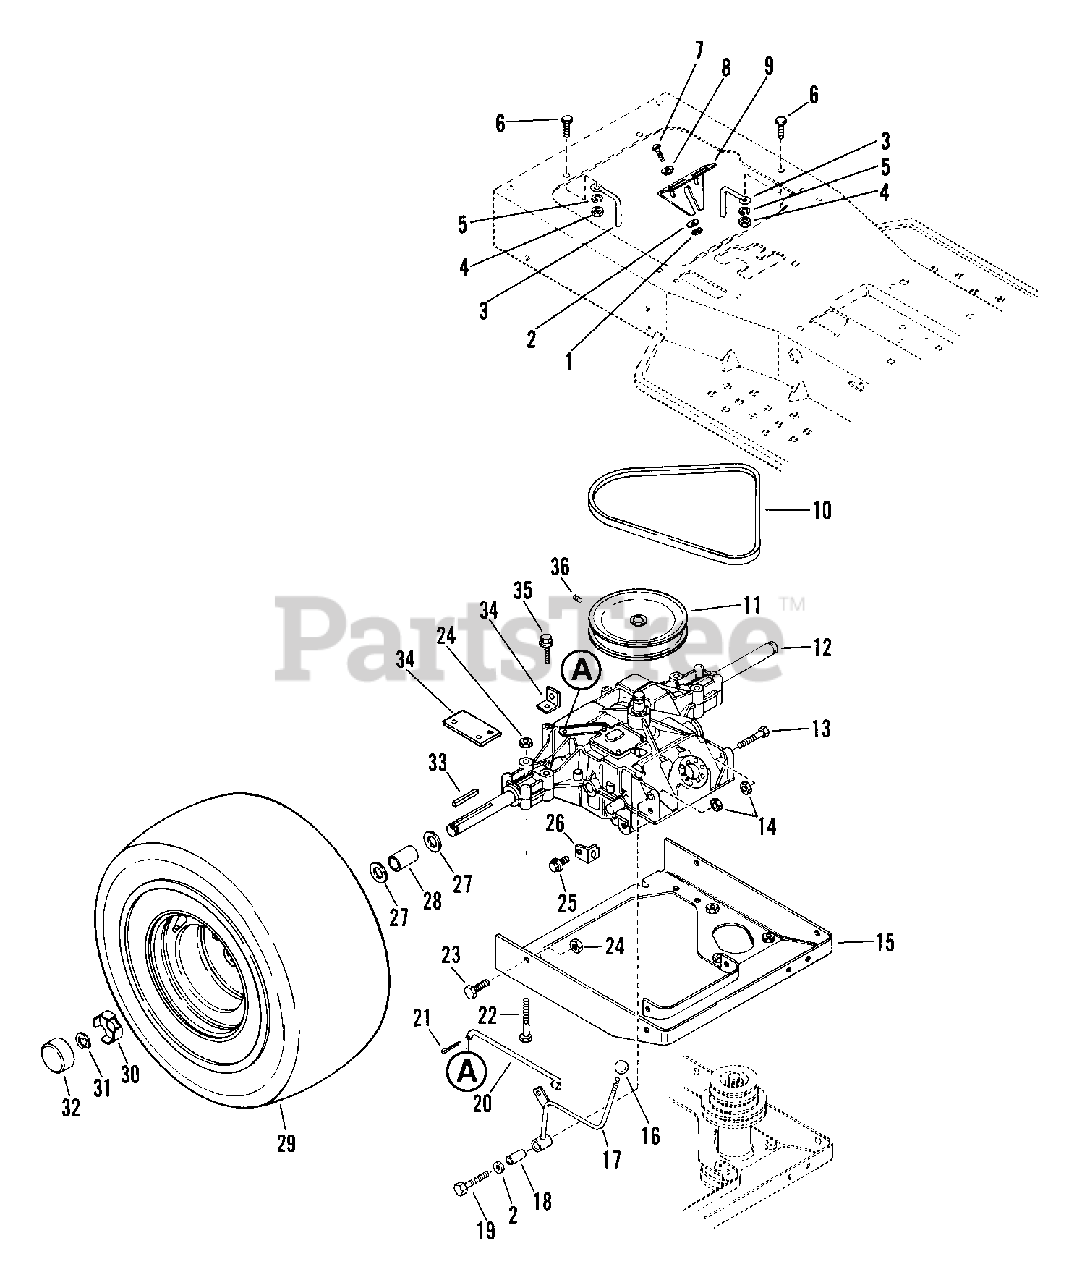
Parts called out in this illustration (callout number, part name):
1	NUT-LK .312-18 GR A PL
2	WSHR-FL-STL.312X.734X.065PL
3	BELT FINGER
4	NUT-HEX .375-16
5	WSHR-LK .375X.094 MED PL
6	BLT-HEX .38-16X1.00 PL
6	BLT-HEX .38-16X1.25 PL GR 2
7	BLT-HEX .31-18X.88 PL GR2
8	SPACER -FLANGED .325X.498X.318
9	CAM ACTUATOR
10	V-BELT, 4L-RAW EDGE
11	PLY-V 6.00 X .63 W/KEY (ADAMS)
12	TRANSAXLE ASSEMBLY
13	BLT-HEX .25-20X1.00 PL GR5
14	NUT-LK TOP .250-20 PL
15	TRANSAXLE MOUNT
16	SHIFT BALL
17	RANGE SELECTOR LEVER
18	SPACER .50 X .32 X 1.00
19	BLT-HEX .25-20X2.00 PL GR5
20	SELECTOR ROD
21	PIN-COTR .09X.75 PL
22	BLT-HEX .38-16X2.75 PL GR5
23	BLT-HEX .38-16X1.00 PL GR5
24	NUT-LK TOP .375-16 GR C YWZC
25	SCR-TAP .312-18X.50 HWH PL TR
26	SPRING ANCHOR
27	WSHR-FL-STL .755X1.375X.062 PL
28	SPACER 1.000 X .760 X 1.562
28	SPACER-RH AXLE 1.007X1.43X.535
28	SPACER-LH AXLE
29	T/WHL ASSY
29	TIRE 18 X 8.50-8
29	WHL
30	SPINDLE CUP
31	RG-RTNG-EXT .750X.050
31	RG-RTNG-EXT 1.00X.078
32	HUB CAP
33	KEY-SQ .188X2.0X.188 SAE 8630
33	KEY-STR .25X2.0X.25
34	TAB
34	ANCHOR PLATE
35	SCR-TAP .250-20X1.31 TTH PL
36	SCR-SET .25-20X.25 SKHCUPNY OH
